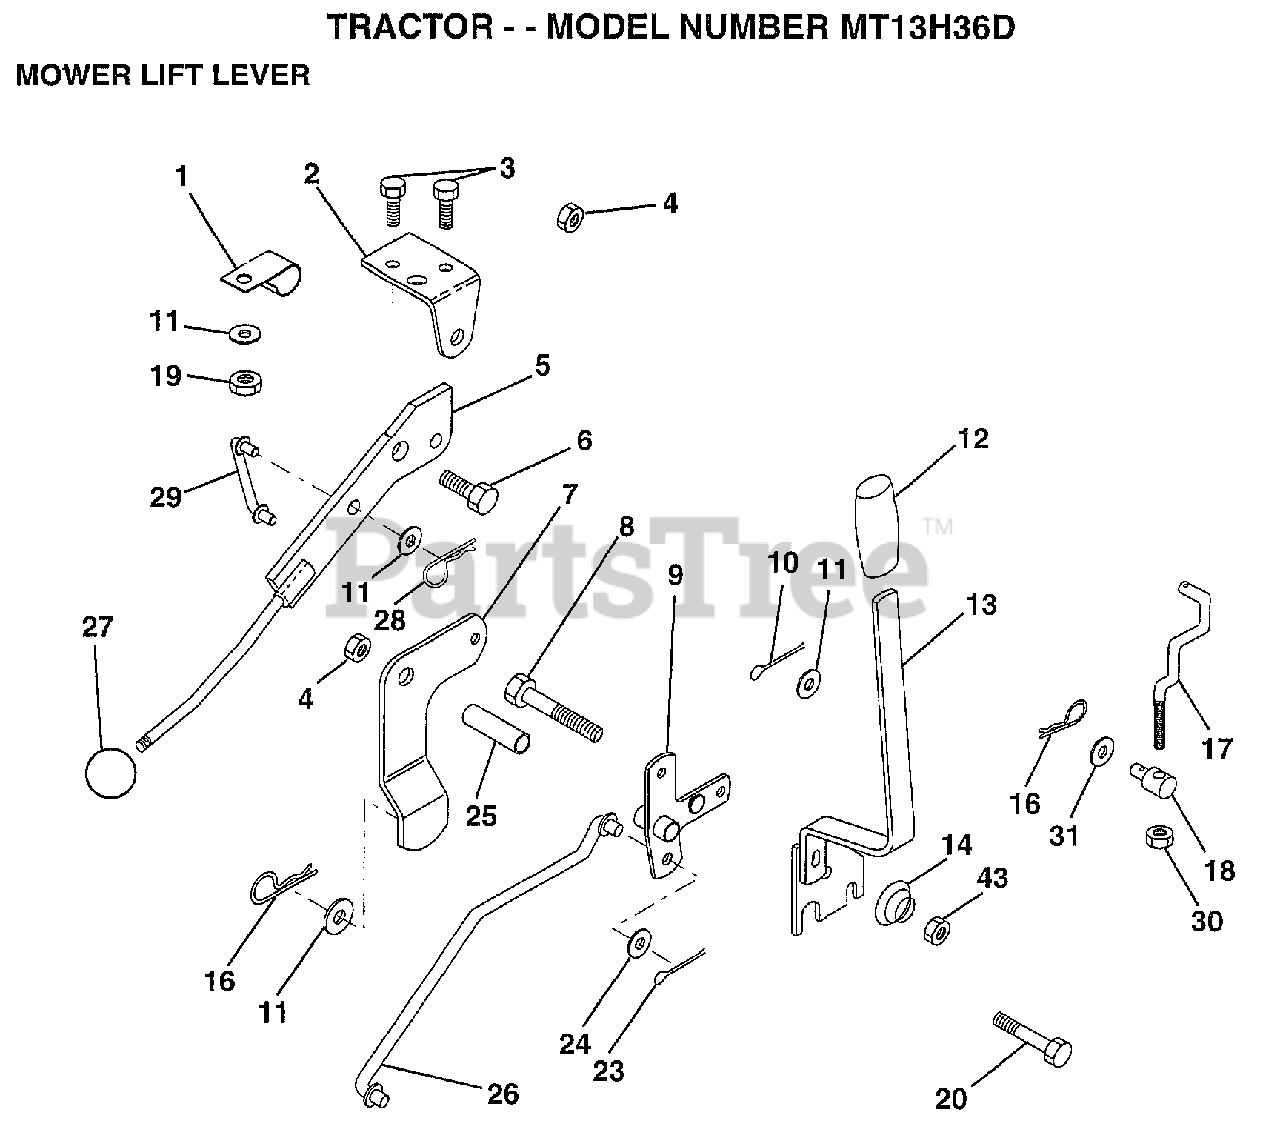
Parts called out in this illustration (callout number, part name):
1	"CLIP,INSULATOR"
2	BRKT CLUTCH
3	BOLT HXHD FIN
5	LEVER.ASM.CLUTCH
6	"BOLT, SHOULDER LT"
7	MWR CLUTCH ARM AS
8	BOLT
9	"BELLCRANK,LIFT"
10	COTTER PIN
11	WASHER
12	GRIP HANDLE
13	HANDLE.ASM.LIFT
14	SPRING COMPRESSIO
16	SPRING.RETAINER
17	"LINK,LIFT FRT"
18	TRUNION ADJ
20	BOLT
23	PIN COTTER 1/8
25	TUBE SPACER
26	ROD LIFT MOWER
27	KNOB
28	RETAINER M
29	CLUTCH LINK
30	NUT
31	WASHER
